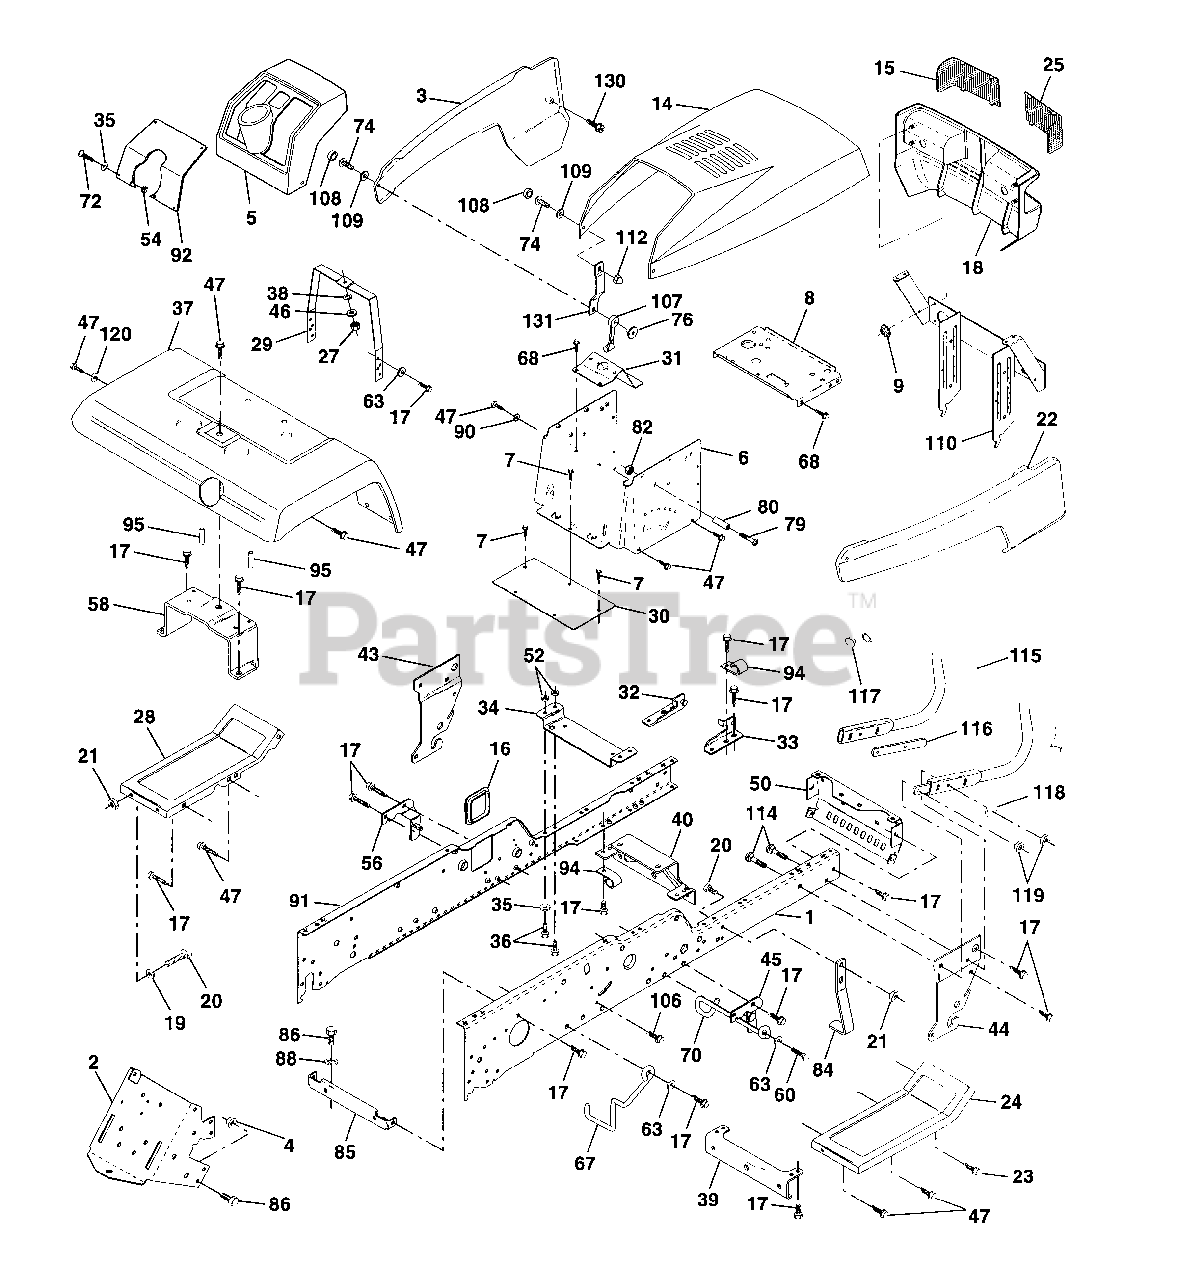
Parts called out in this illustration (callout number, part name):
1	Rail, Frame RH
2	Drawbar, Gt
3	Panel Asm., Side LH
4	Nut, Lock Hex 7/16 Unc
5	Dash, Plastic Black
6	Dash 1-PCS, Lower
7	Screw, Thd Cut 1/4-20 x 1/2
8	Support, Battery
14	Hood Asm., Pnt
15	Lens, Headlight RH
16	Cover, Access
17	Screw, Thdrol 3/8-16 x 3/4
18	Grille
19	Washer 13/32 x 13/16 x 12 Ga.
20	Bolt, Fin Hex 3/8-16 x 1
21	Nut, Crownlock 3/8-16 Unc
22	Panel Asm., Side RH
23	Screw Thdrol. 3/8-16 x 1 Ty-TT
24	Footrest, RH
25	Lens Headlight LH
27	Nut Fin Hex 1/4-20
28	Footrest, LH
29	Bracket, Support Dash
31	Brace, Support Steering
32	Bracket Asm., Frame Pivot Lh
33	Bracket Asm., Frame Pivot Rh
34	Bracket, Engine Support Rear
35	Washer 11/32 x 11/16 x 16 Ga.
36	Bolt, Fin Hex 5/16-18 x 3/4
37	Fender, Pnt.
38	Washer, Lock 1/4
39	Bracket, Axle Front
40	Bracket, Support Axle/Engine
43	Bracket, Spnsn Front Lh
44	Bracket, Spnsn Front Rh
45	Bracket Asm., Susp Chassis Rh
46	Washer 9/32 x 3/4 x 16 Ga.
47	Screw Thdrol 3/8-16 x 1/2
50	Bracket, Chassis Front
52	Locknut, Hex W/Ins 5/16-18 Unc
54	Nut 5/16-18
56	Bracket Asm., Susp Chassis Lh
58	Bracket Asm., Fender
60	Screw Thdrol 3/8-16 x 1-1/4
63	Washer 13/32 x 1 x 14 Ga.
67	Guide Belt Trans VGT
68	Screw, Thdrol 5/16-18 x 1/2
70	Guide, Belt Mid Span
72	Screw, Mach Trhd 5/16-18 x 3/4
74	Screw, Machine #10-24
76	Nut, Weld #10-24
79	Screw, Machine #10-24 x 1/4
80	Spacer, Split
82	Nut #10-24
84	Stop, Over Center 44" 20/23" T. 94
85	Bracket Support Pnt Trans VGT
86	Bolt, Fin Hex 7/16-14 Unc x 1
88	Washer Lock Hvy Hlcl Spr 7/16
90	Washer, Lock External Tooth 3/8
91	Rail, Frame Lh
92	Plate, Silkscreen Dash
94	Clip, Fuel Line
95	Push Nut, Nylon
106	Screw Thdrol. Hex Hd Zinc Mur
107	Latch, Chute Blk
108	Cap, Snap Black
109	Cap, Washer Snap
110	Pivot Asm. Grille/Hood Husq. VGT
112	Nut, Acorn, Hex #10-24
114	Bolt, Carriage 3/8-16 x 1-1/4
115	Bumper Asm
116	Bracket Extension Bumper
117	Plug Plastic
118	Washer 13/32 x 13/16 x 16 Ga.
119	Nut Crownlock 3/8-16 UNC
120	Washer 13/32 x 1 x 16 Ga.
130	Screw, SLTD Hex Hd. W/Pl Washer
131	Bracket Support Hood/Panel YP
